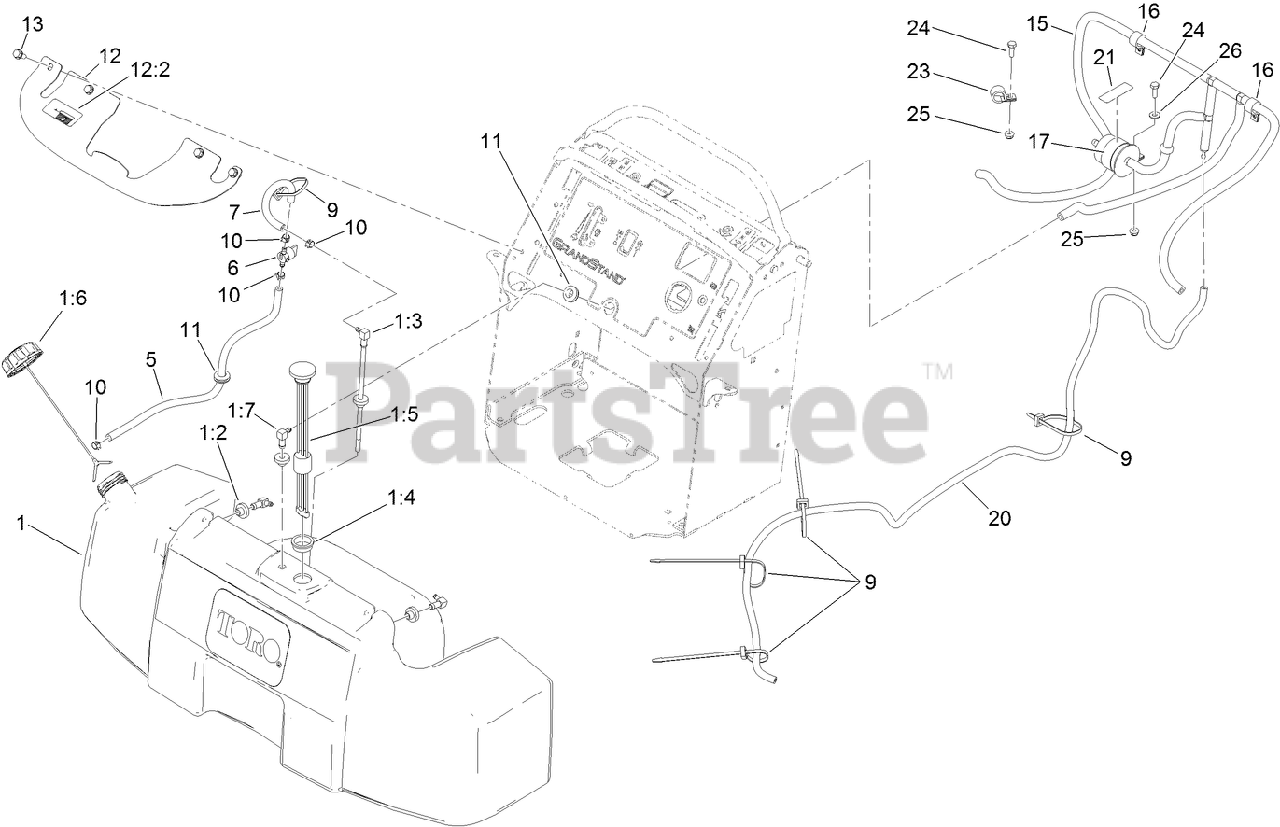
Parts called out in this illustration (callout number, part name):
1	TANK ASM
1:2	BUSHING
1:3	FITTING-FUEL, SCREEN TUBE
1:4	GROMMET
1:5	GUAGE-FUEL
1:6	CAP-FUEL
1:7	ELBOW-90 DEG
5	HOSE-FUEL
6	VALVE-FUEL
7	HOSE-FUEL
9	TIE-CABLE
10	CLAMP-HOSE
11	GROMMET
12	BRACKET-TANK
12:2	DECAL-FILL, FUEL
13	SCREW-HWHTF
15	VENT HOSE ASM
16	CLAMP-CABLE
17	CLAMP-R
20	HOSE-FUEL
21	DECAL-FILTER, EMISSIONS
23	CLAMP-CABLE
24	SCREW-HH
25	NUT-HF
26	WASHER-FLAT
